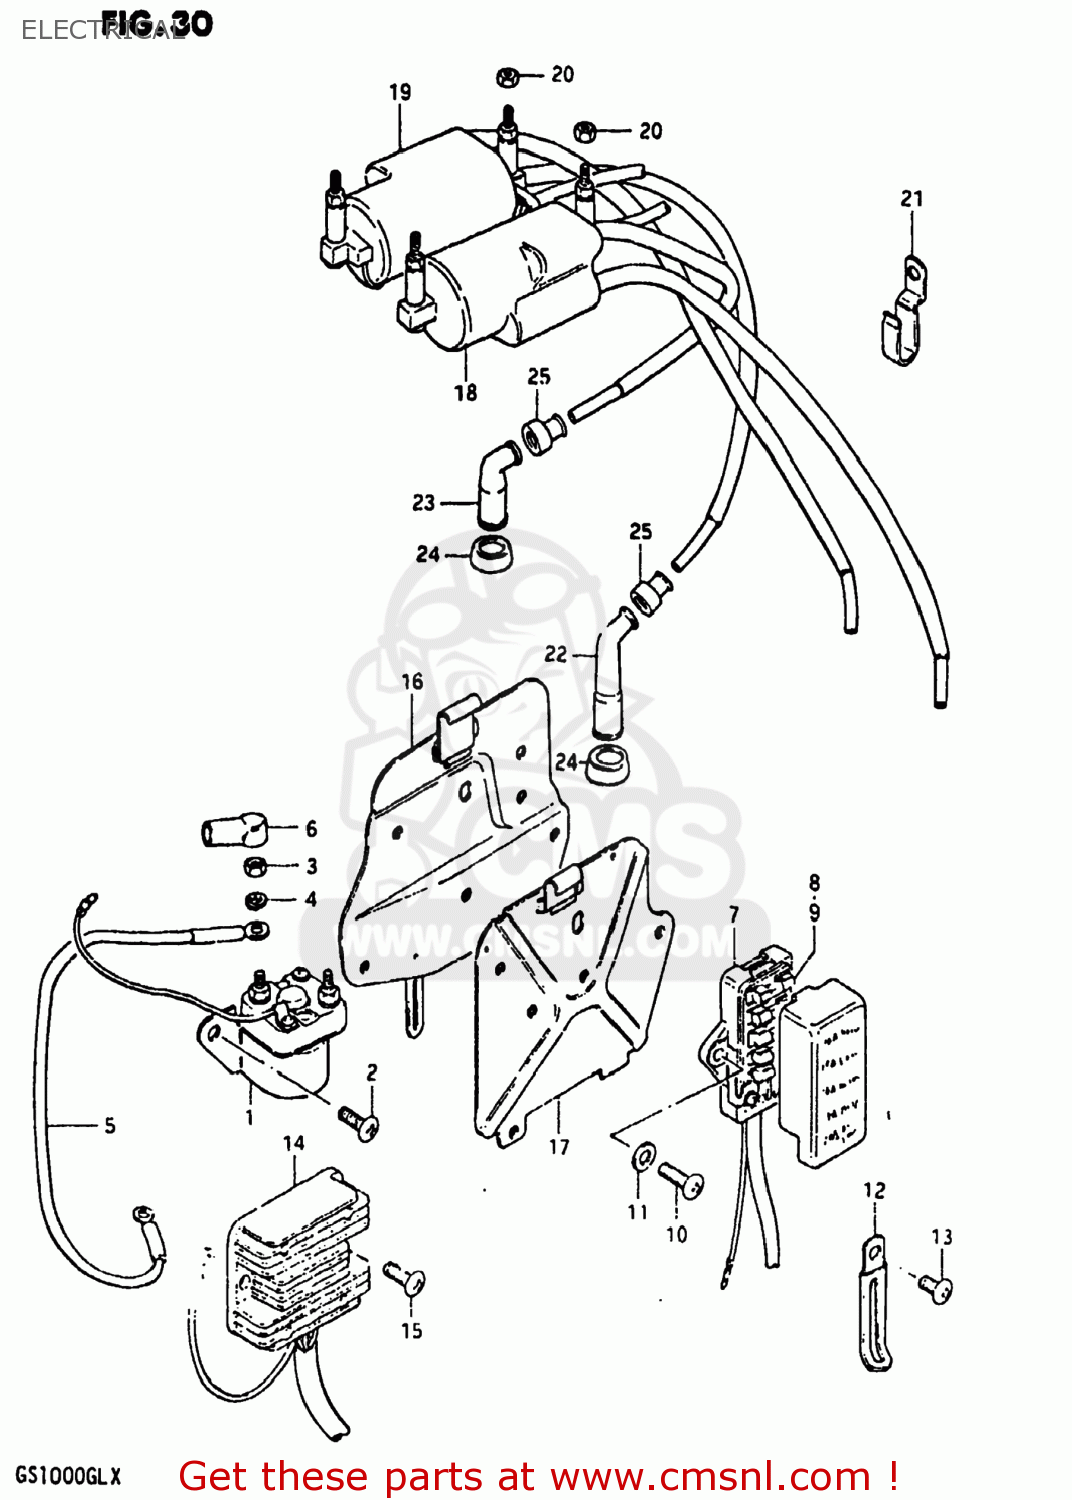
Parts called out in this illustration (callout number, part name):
1	RELAY ASSY,STARTING MOTOR
2	SCREW
3	NUT 6MM
4	LOCK WASHER
5	WIRE,STARTER MOTOR LEAD
6	CAP,STARTER RELAY
7	BOX ASSEMBLY,FUSE
8	FUSE(10A)
9	FUSE(15A)
10	SCREW
11	WASHER
12	CLAMP L:35
13	SCREW
14	RECTIFIER ASSEMBLY
15	SCREW 6X12
16	HOLDER COMP,ELECTRONIC PARTS
17	HOLDER COMP,ELECTRONIC PARTS
18	COIL ASSEMBLY,IGNITION
19	COIL ASSEMBLY,IGNITION
20	NUT
21	CLAMP
22	CAP ASSY,SPARK PLUG
23	CAP,SPARK PLUG
24	SEAL,SPARK PLUG
25	SEAL,SPARK PLU
